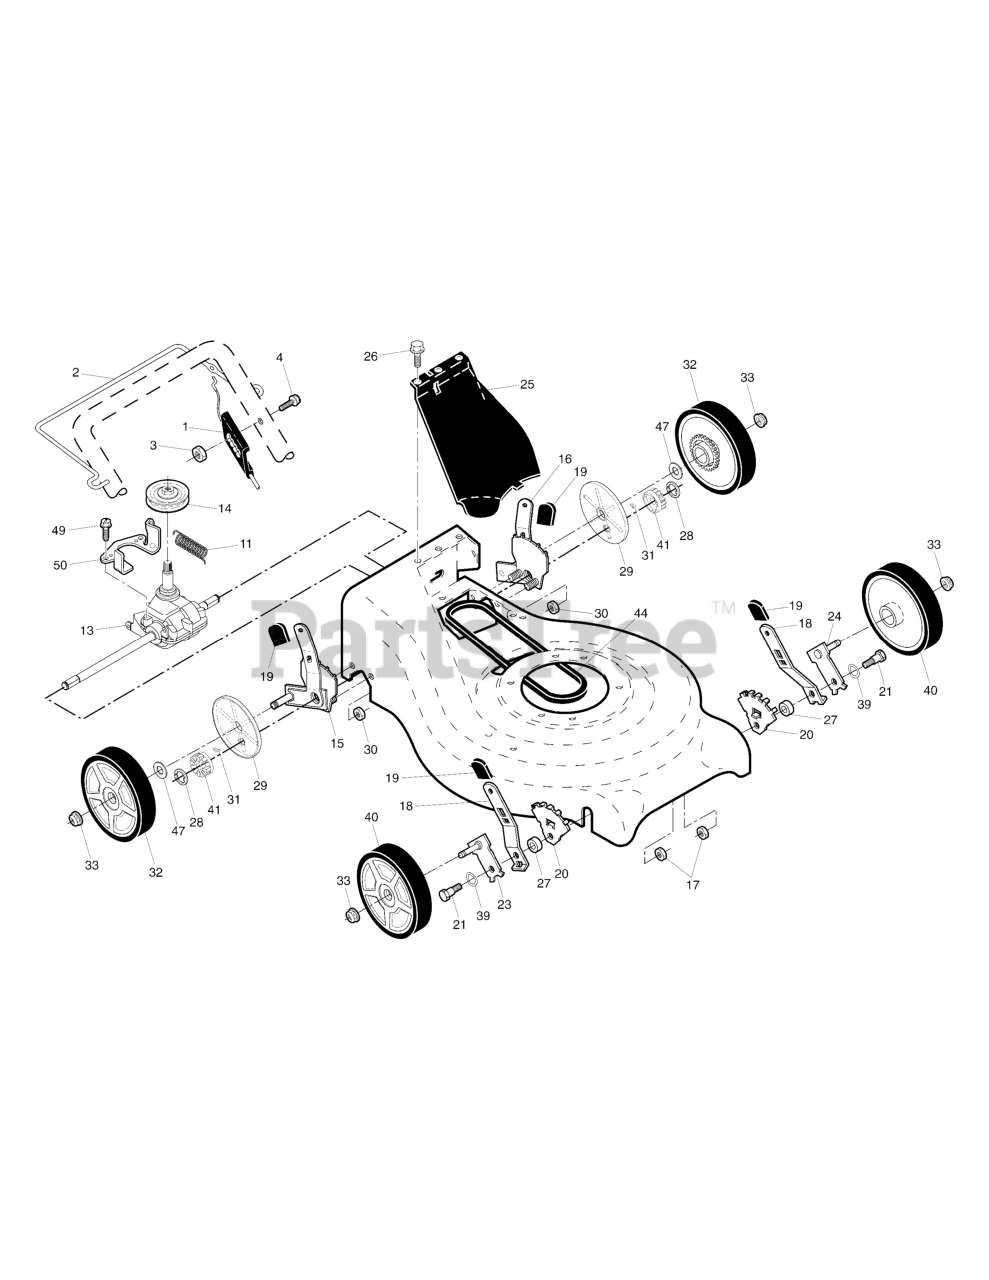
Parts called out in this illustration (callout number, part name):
1	** Drive Control Assembly (Includes Cable)
2	Bar, Drive Control
3	Nut, Hex
11	Spring, Return
13	** Gear Case Assembly, Complete
14	** Pulley, Drive
15	** Kit, Wheel Adjuster Assembly, RH (Includes Knob and Bearing)
16	** Kit, Wheel Adjuster Assembly, LH (Includes Knob and Bearing)
17	Nut, Hex
18	Spring, Selector
19	Knob, Selector Spring
20	Bracket, Wheel Adjusting
21	Bolt, Shoulder
23	Axle Arm Assembly, RH
24	Axle Arm Assembly, LH
25	** Cover Drive
26	Screw, Threaded, Rolled #10-25 x .50
27	Spacer
28	E-Ring 7/16
29	Cover, Dust, Wheel
30	Nut, Hex
32	** Wheel & Tire Assembly, Rear
33	Nut, Flangelock 3/8-16
39	Washer, Curved, Cylindrical
40	Wheel & Tire Assembly, Front
41	** Pinion, Gear
44	** V-Belt
47	Washer
49	Screw, Hi-Lo Thread #12 x 5/8
50	** Belt Keeper
